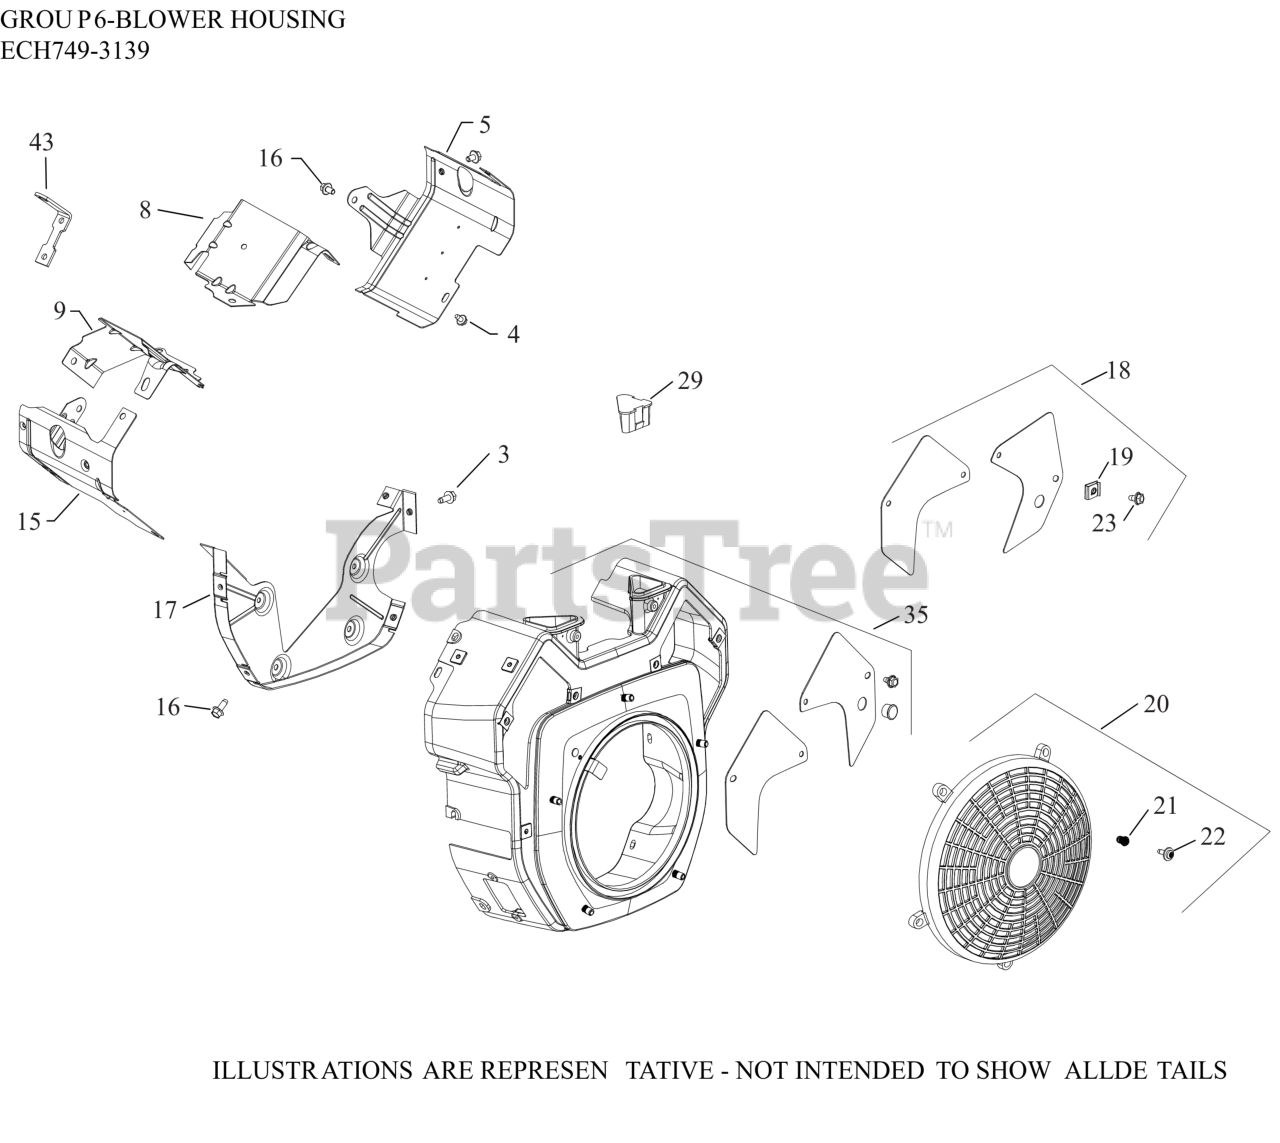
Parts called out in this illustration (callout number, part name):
3	SCREW, THREAD FORMING
4	SCREW, THREAD FORMING
5	BAFFLE, RIGHT BARREL
8	BAFFLE, VALLEY #1 CYLINDER
9	BAFFLE, VALLEY #2 CYLINDER
15	BAFFLE LEFT BARREL
16	SCREW, THREAD FORMING
17	PLATE, BACKING
17	KIT, BACKING PLATE
18	KIT, ACCESS PANEL
19	CLIP, BAFFLE MOUNTING
20	KIT, FIXED GUARD
21	INSERT, THREADED (M5)
22	SCREW, SEMS
23	SCREW, THREAD FORMING
29	COVER, BLOWER HOUSING
35	KIT, BLOWER HOUSING
43	STRAP, LIFTING
